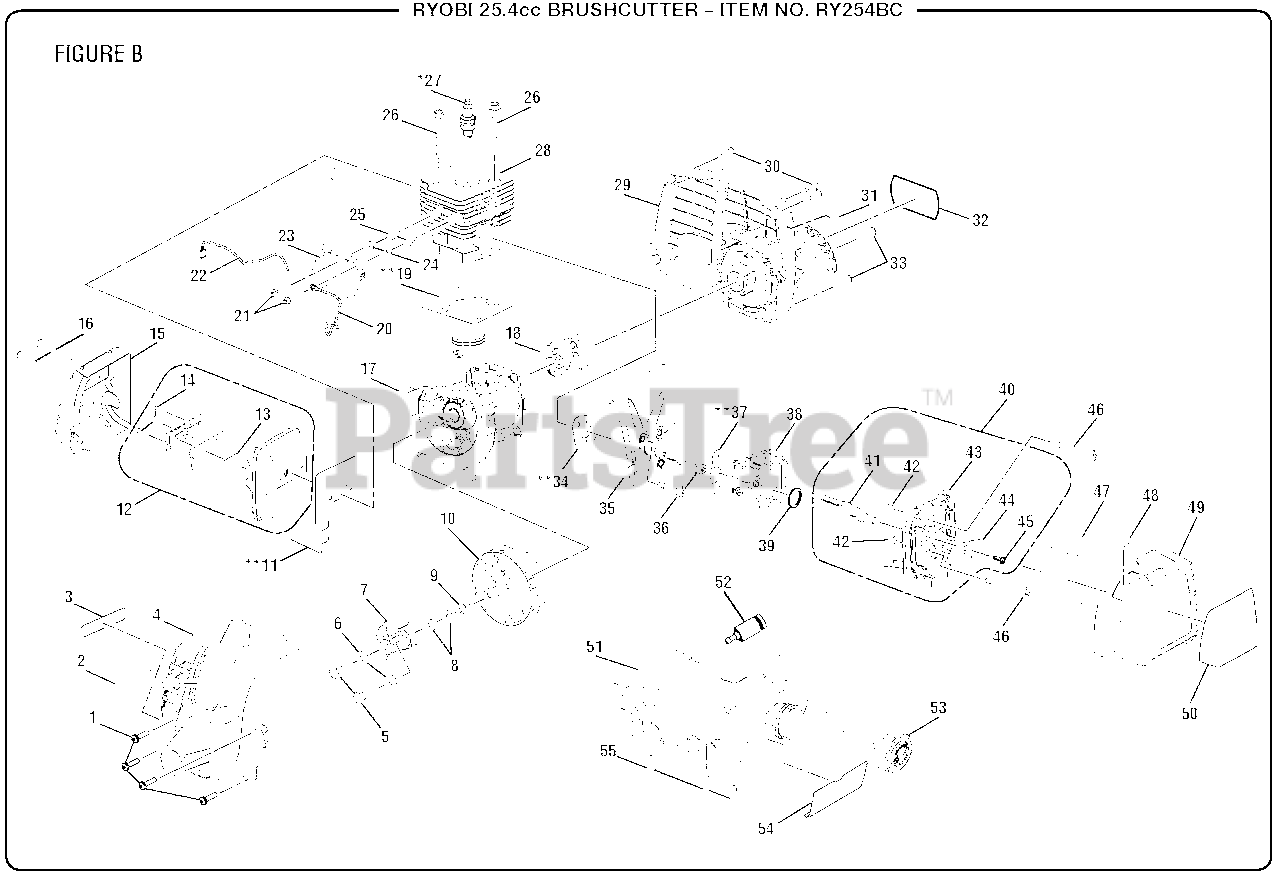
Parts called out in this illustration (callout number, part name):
1	Screw w/Washer (M5 x 20 mm, T20 Torx Pan Hd.)
2	Logo Label (Front)
3	Combustion Warning Label
4	Front Housing Assembly
5	Clutch Shoulder Bolt (M6 x 22.5 mm, Hex Hd.)
6	Curved Washer
7	Clutch Assembly
8	Washer (ID6 x OD15 x 1.2t)
9	Flywheel Nut
11	Muffler Gasket
12	Muffler Assembly
13	Screen
14	Screw (6-20 x 1/4 in., T20 Torx Pan Hd.)
15	Heat Shield
16	Screw (M5 x 50 mm, T25 Torx Pan Hd.)
17	Crankcase Assembly
18	Starter Cup
19	Gasket
20	Lead Wire (Red)
21	Screw w/Washer (M4 x 19 mm, T20 Torx Pan Hd. S.T.)
22	Lead Wire (Black)
23	Coil Boot Assembly
24	Washer (ID4.2 x OD10 x 1t)
25	Spacer (Phenolic)
26	Screw (M5 x 22 mm, Soc. Hd.)
27	Spark Plug (Champion RCJ4)
29	Rear Housing and Starter Assembly
30	Screw (M4 x 18 mm, T20 Torx Pan Hd. S.T.)
31	Primer Bulb Location Label
32	Logo Label (Rear)
33	Cap Screw w/Washer (M5 x 16 mm, T25 Torx Soc. Hd.)
34	Insulator Gasket
35	Heat Dam Insulator
36	Screw (M5 x 27 mm, T25 Torx Pan Hd. S.T.)
37	Gasket
38	Carburetor Assembly
39	Carburetor O-Ring
40	Airbox Base Assembly
41	Choke Lever
42	Compression Limiters
43	Air Box Base
44	Choke Plate
45	Screw (M4 x 12 mm, T20 Torx Pan Hd. S.T.)
46	Screw (M5 x 44 mm, T20 Torx Pan Hd.)
47	Air Filter
48	Choke Position Label
49	Airbox Cover
50	Starting Instructions Label
51	Fuel Tank and Cap Assembly
52	Fuel Filter
53	Fuel Cap Assembly
54	Fuel Mixture Label
55	Shoulder Screw (M4 x 14 mm, T25 Torx Truss Hd. S.T.)
